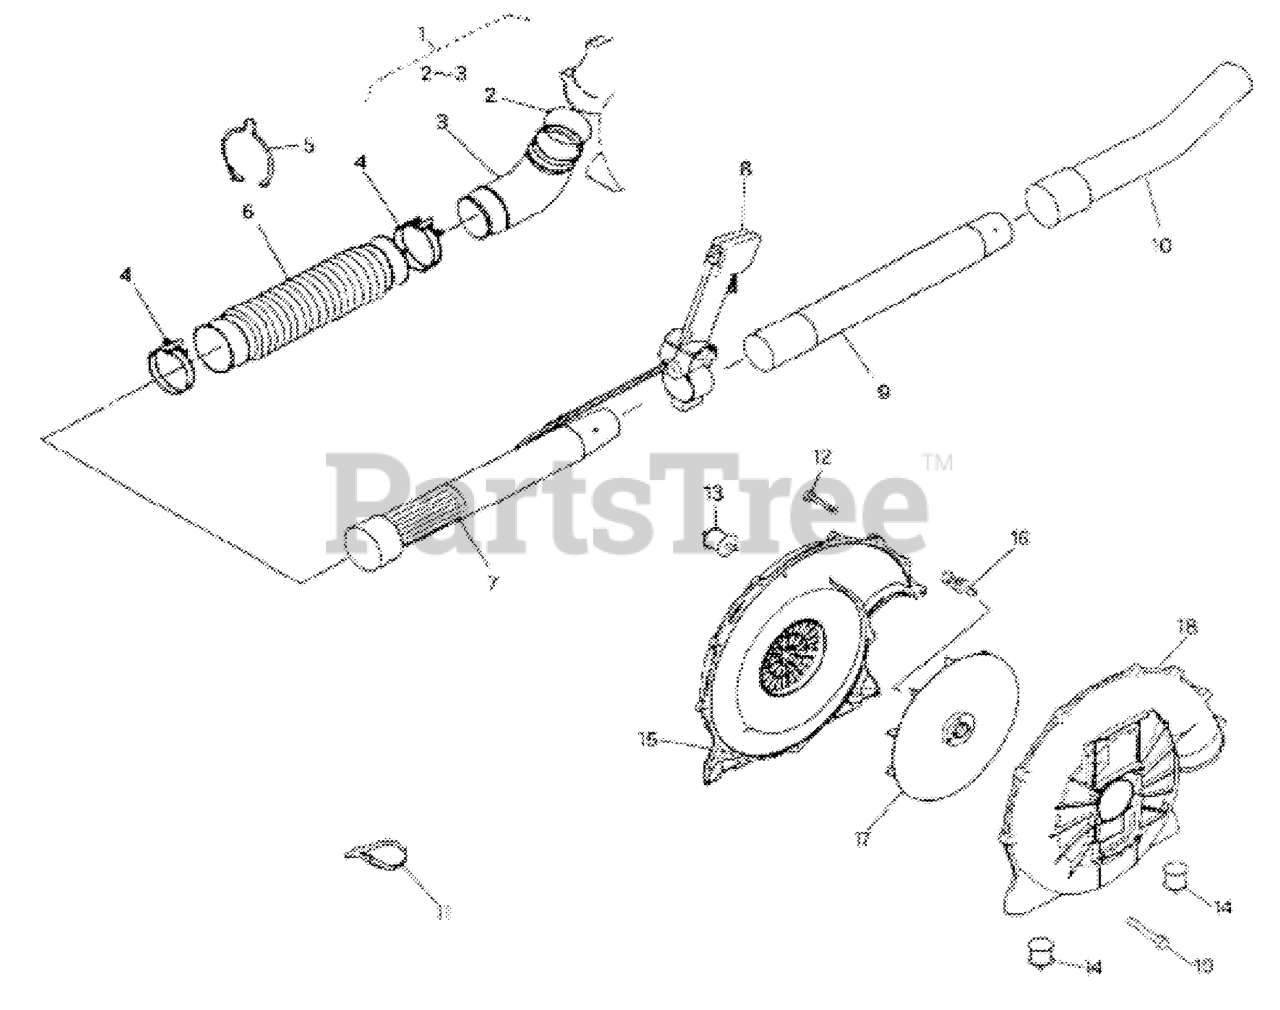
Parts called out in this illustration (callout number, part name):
1	ELBOW PIPE C.P.
2	O'RING
3	ELBOW PIPE
4	HOSE BAND
5	CLAMP
6	FLEX. PIPE 36084-101
7	BASE PIPE
8	THROTTLE ASSEMBLY
9	MIDDLE PIPE
10	BEND PIPE
11	BAND FR66820XX006
12	SCREW
13	ANTIVIBE MOUNT
14	ANTIVIBE MOUNT
16	BOLT
19	BOLT
